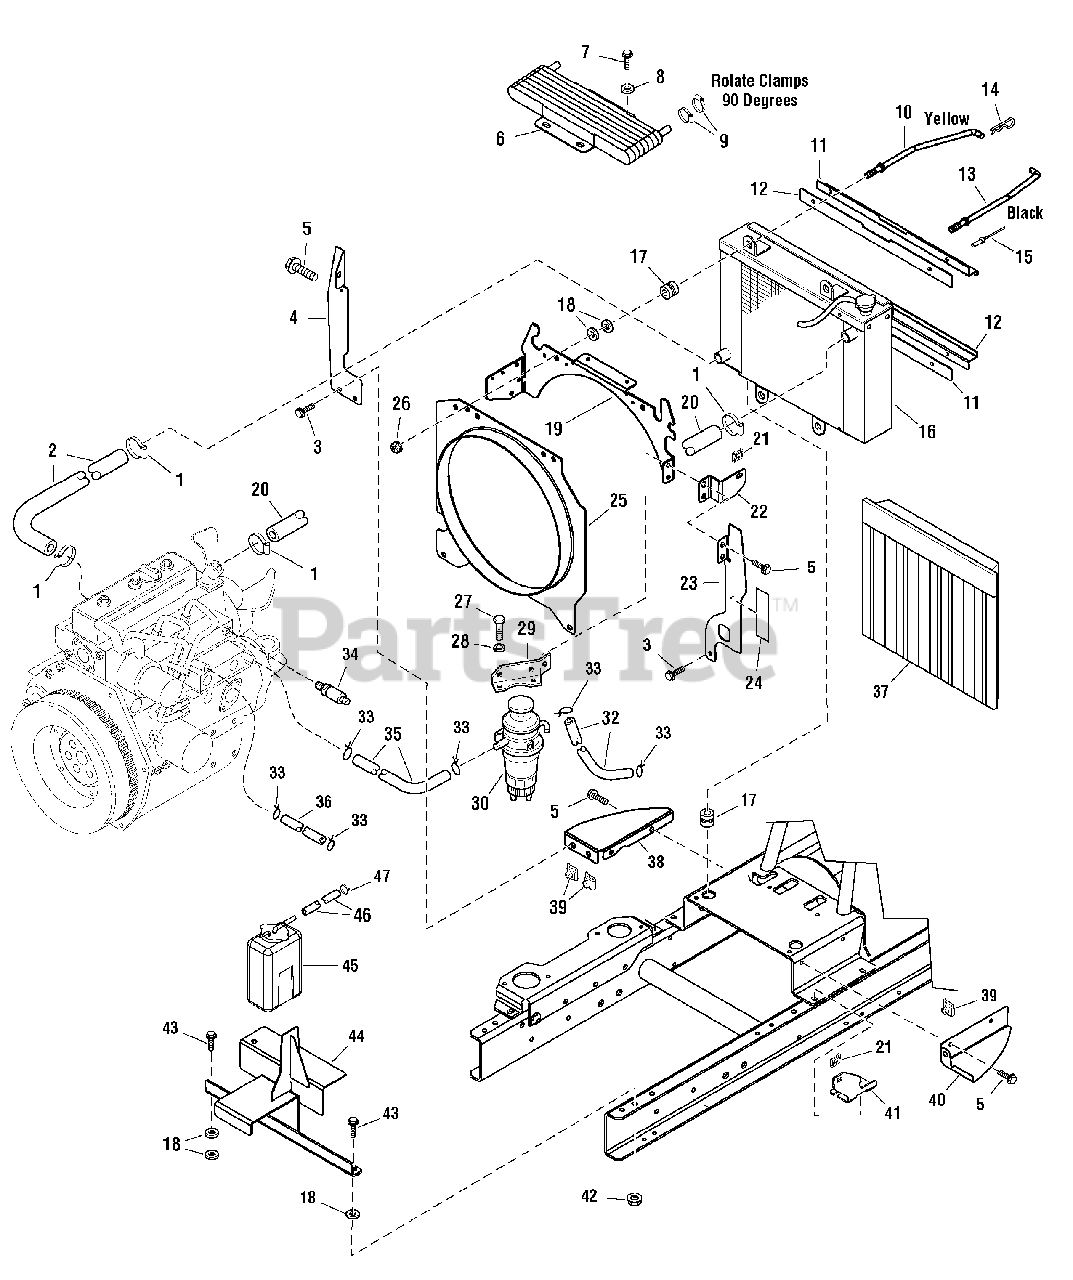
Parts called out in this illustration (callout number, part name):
1	CLAMP, Hose, Worm
2	HOSE, Radiator
3	SCREW, Hex, Whiz Lock, Flange, 5/16-16 x 1-1/4
4	SHIELD, R.H., 16GA
5	SCREW, Hex, Washer Head, Taptite, 5/16-18 x 3/4
6	COOLER ASSEMBLY, Oil
7	SCREW, Hex, Washer Head, Taptite, 1/4-20 x 1/2
8	WASHER, 1/4
9	CLAMP, Hose
10	ROD, Radiator, R.H.
11	SLIDE, Offset, 14GA
12	SLIDE, Screen Flat, 14GA
13	ROD, Radiator, L.H.
14	PIN, Quick
15	RIVET, Pop
17	SPACER
18	WASHER, 3/4
19	SUPPORT, Radiator Shroud, 10GA
20	HOSE, Radiator
21	CLIP, 1/4 Turn Push
22	COVER, Bracket, Top, 12GA
23	SHIELD, L.H., 16GA
24	DECAL, Clean Radiator
25	SHROUD, Radiator
26	NUT, Hex, Flange, 3/8-16 ESNA
27	SCREW, M8 - 1.25 x 20mm, Hex Head
28	LOCKWASHER, Spring, 5/16
29	BRACKET, Fuel Filter
30	* FUEL FILTER ASSEMBLY
31	* FILTER, Fuel
32	HOSE, Fuel
33	CLAMP, Hose
34	SENDER, Temperature
35	HOSE, Fuel
36	HOSE, Fuel (Cut to 71.5)
37	SCREEN, Corrugated, 20GA
38	BAFFLE, R.H., 16GA
39	NUT, Speed, Lug Type, 5/16-18
40	BAFFLE, L.H., 16GA
41	COVER, Bracket, Bottom
42	NUT, Hex, KEPS, Conical Washer, 3/8-16
43	SCREW, Hex, Whiz Lock, Flange, 3/8-16 x 1-1/4
44	HOLD DOWN ASSEMBLY, Battery
45	* RADIATOR, Overflow
46	* HOSE, Radiator Overflow
47	CLAMP, Hose, Worm
